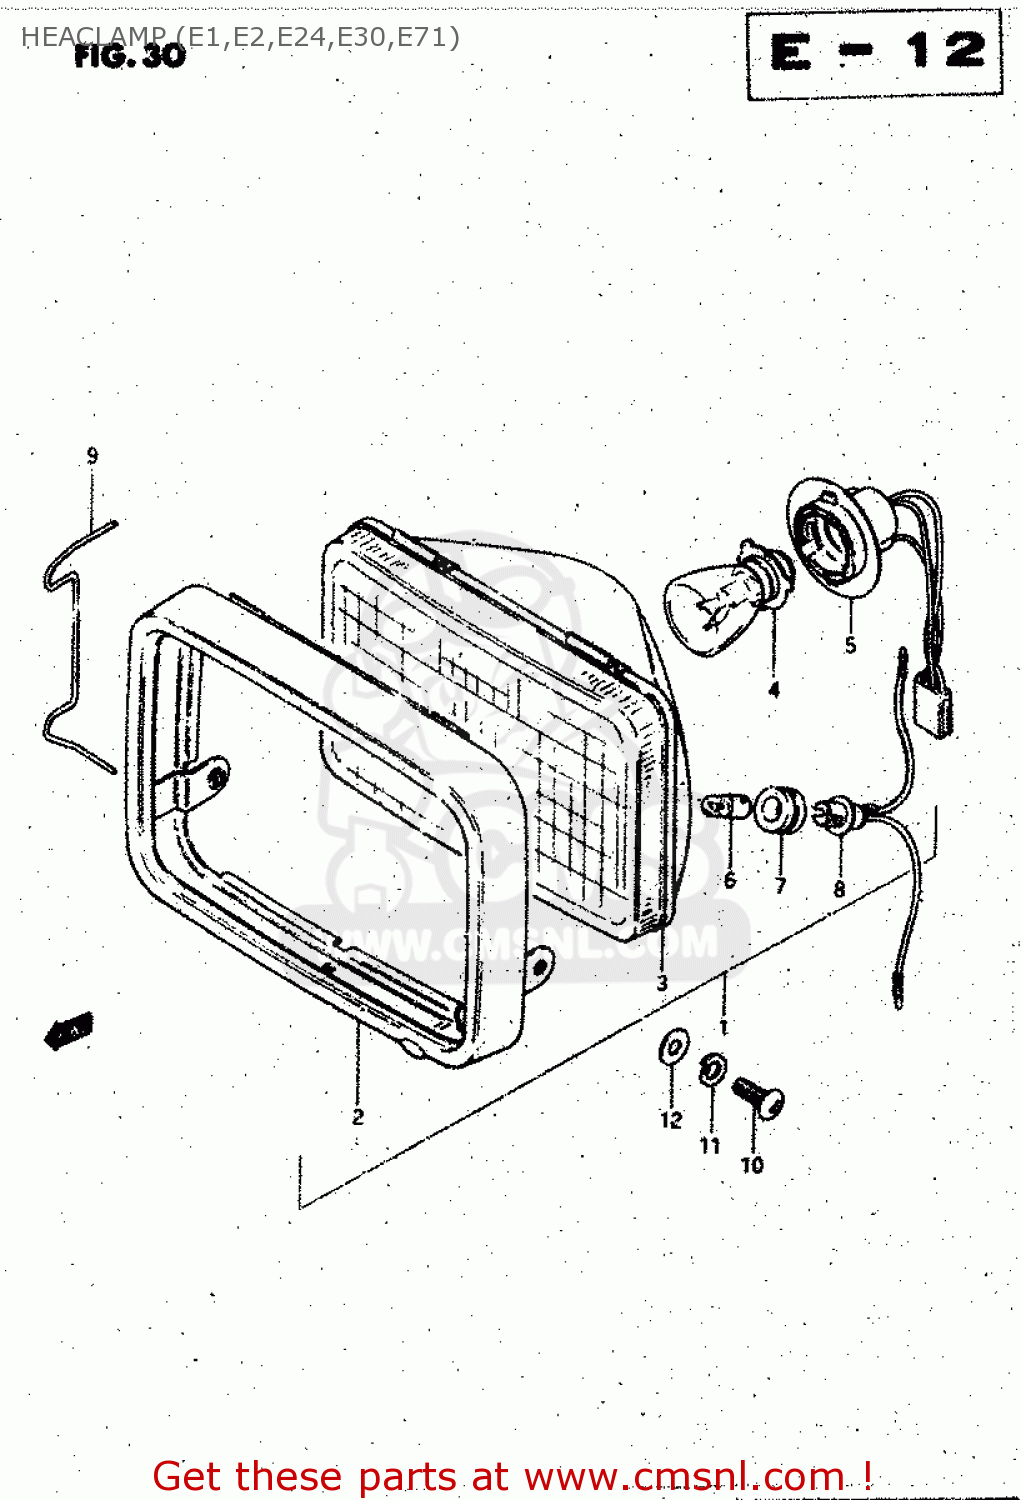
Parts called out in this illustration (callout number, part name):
1	HEADLAMP ASSY
2	RIM
3	LAMP UNIT
4	BULB 12V35/35W
5	SOCKET
6	BULB(12V3.4W,STANLEY,A72A)
7	JOINT,RUBBER
8	SOCKET
9	SPRING
10	SCREW
11	LOCK WASHER
12	WASHER
